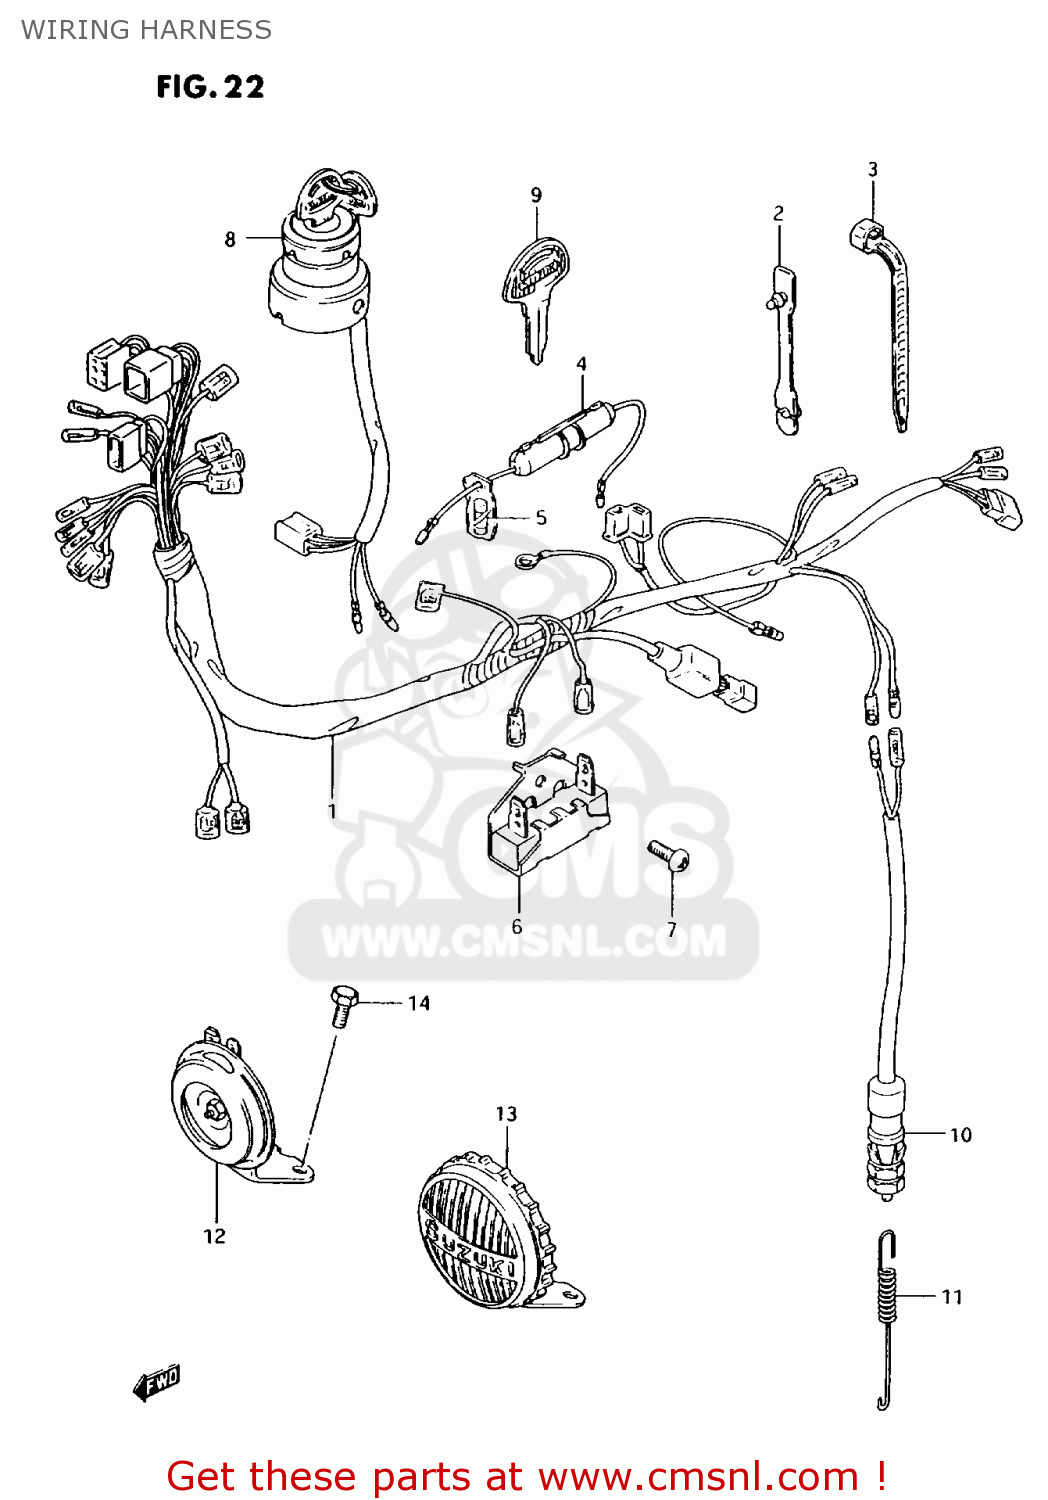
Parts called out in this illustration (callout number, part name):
1	WIRING HARNESS
2	CLAMP,L:88
3	CLAMP L:165
4	CASE ASSY,FUSE
5	FUSE(10A)
6	RESISTOR ASSY,LAMP(2 OHM)
7	SCREW
8	SWITCH ASSY,IGNITION
9	KEY,BLANK
10	SWITCH ASSY,STOP LAMP
11	SPRING
12	HORN ASSY
13	HORN ASSY
14	BOLT
